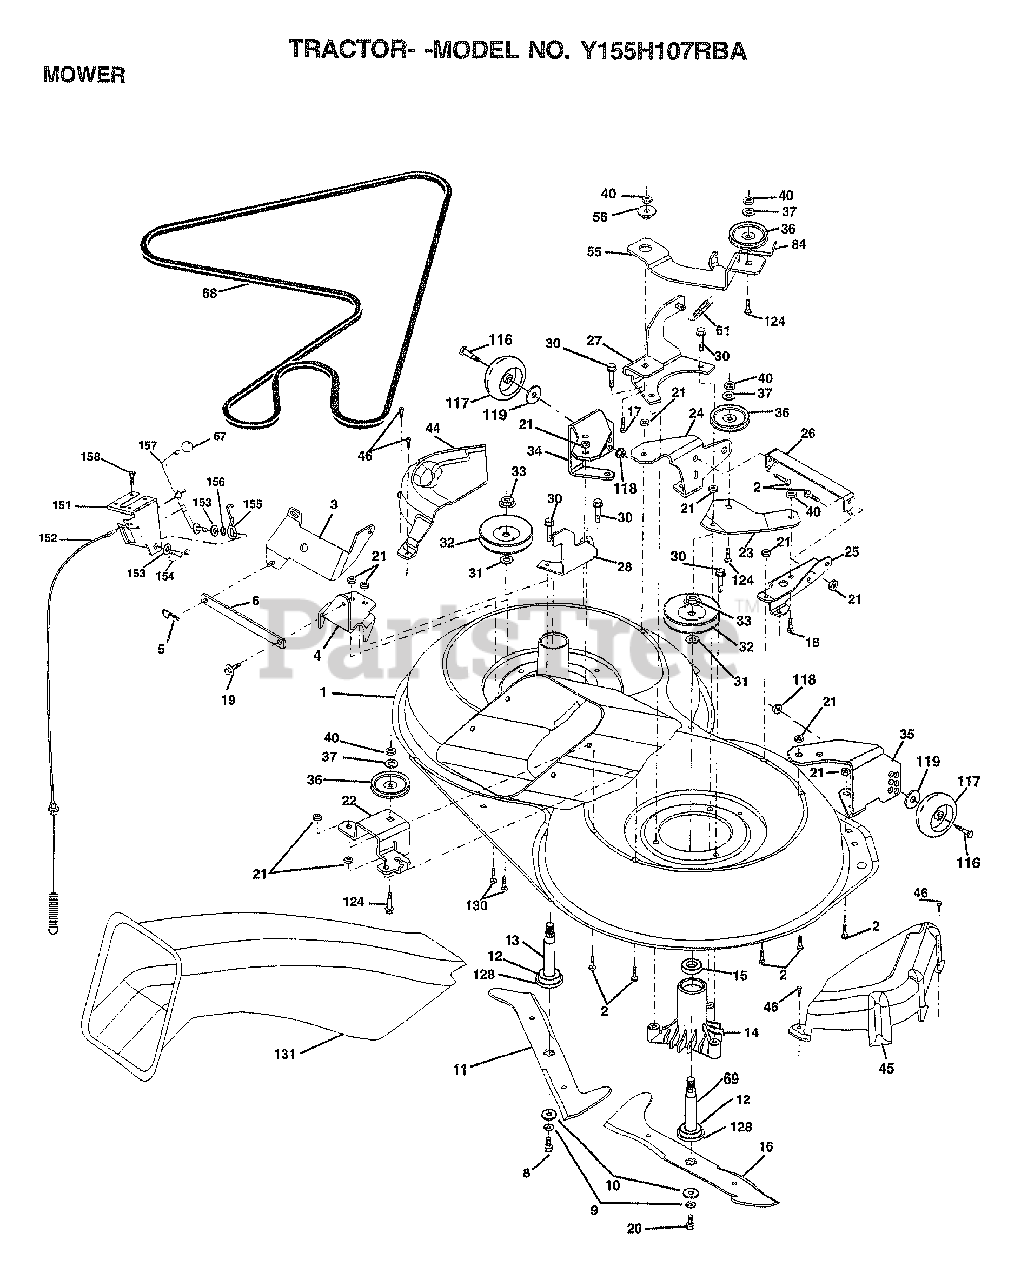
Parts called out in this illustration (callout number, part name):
1	HOUSING ASM MOWER
2	BOLT
3	BRKT.ASM.S-BAR.CHASSIS
4	BRKT BAR SWAY DECK
6	BAR.SWAY.92.CRD
8	BLADE BOLT
10	WASHER.HARD.BLADE
12	BEARING.BALL
14	HSG ASM MANDREL
15	BEARING
16	BLADE
18	BOLT D
19	BOLT SHD 5/16-18
20	BOLT.3/8-24X1.25
22	BRKT IDLER SPRT
23	BRKT IDLER SPRT
24	BRKT SUSPENSION
25	BRKT SUSPENSION
26	BRACE.SUPT.SUSP.FRT.CRD
27	BRKT ASM SUSP
28	BRKT ASM SUSP
30	"SCREW-THD ROLL,WA"
31	WASHER
32	PULLEY.MANDREL.42
34	BRKT GAUGE WHEEL
35	BRKT GAUGE WHEEL
36	PULLEY.IDLER.4.25
37	WASHER
38	SPACER HUB ARM IDLER
39	BOLT
44	COVER MANDREL
45	COVER MANDREL
46	SCREW.1/4-20X5/8
55	ARM IDLER
61	SPRING.TENSION.BELT
67	KNOB T(3/8 HOLE)
68	HEX-BELT
69	SHAFT.ASM.W/LWR.BRG.RH.THD
84	"KEEPER-BELT,IDLER"
116	BOLT.SHOULDER
117	WHEEL GAGE DONUT
118	LOCKNUT
119	WASHER
124	BOLT.3/8-16X1.50
128	WASHER.FELT.
131	CHUTE.BAGGER.CRD
151	BRKT CLUTCH CABLE
152	CABLE CLUTCH CRD SERVICE
153	WASHER FLAT
154	SPRING RETAINER
155	SPRING RETENTION LVR CLUTCH CAB
156	SPACER
157	ROD.CLUTCH.CABLE.3/8
158	SCREW LT
